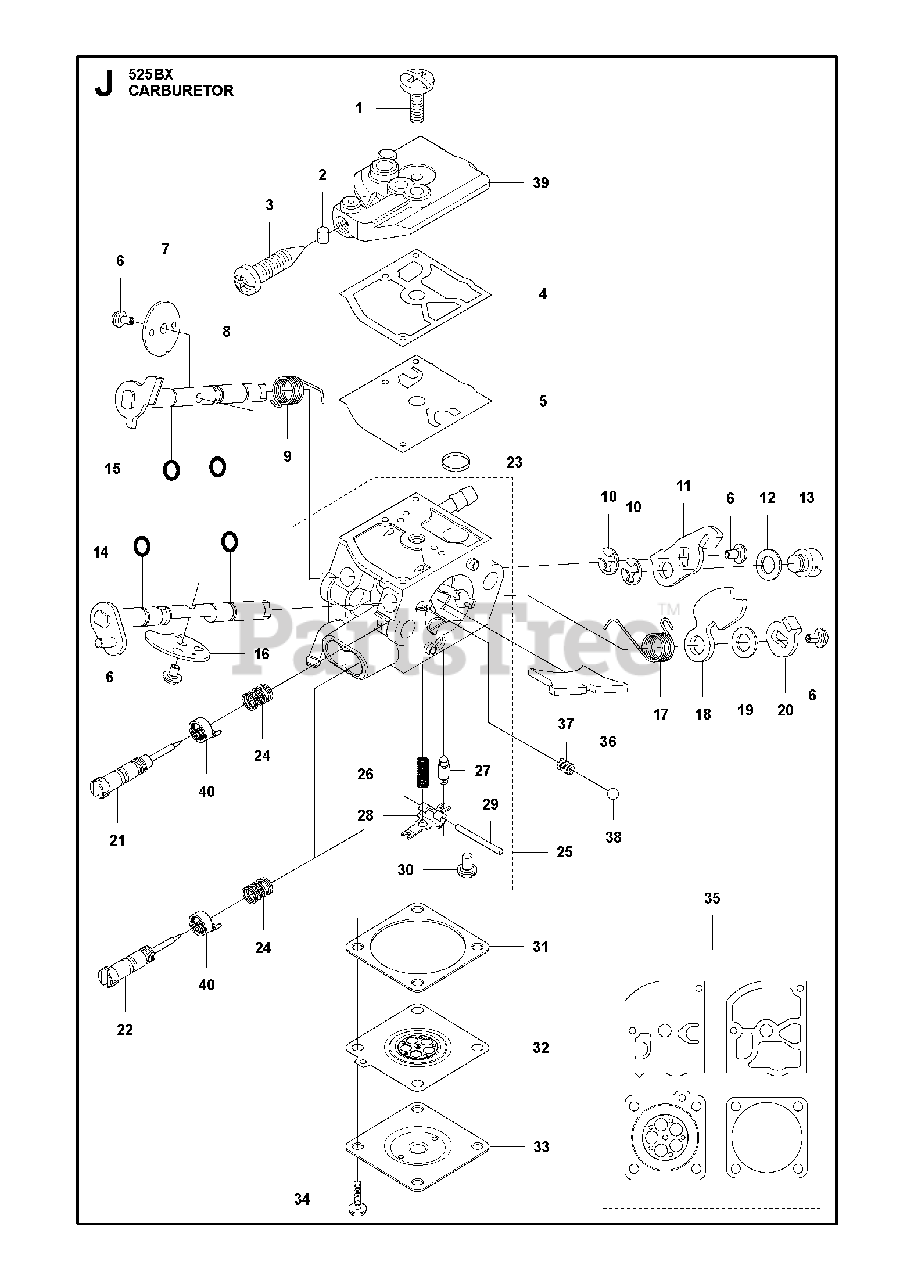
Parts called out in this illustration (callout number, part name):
4	GASKET PUMP
5	DIAPHRAGM PUMP
7	VALVE THROTTLE
8	SHAFT ASSY THROTTLE
9	SPRING THROTTLE RETURN
14	SHAFT ASSY CHOKE
16	VALVE CHOKE
17	SPRING RETURN
21	SCREW IDLE MIXTURE
22	SCREW MAIN MIXTURE
25	BODY ASSY, CARBURETTOR
26	SPRING
27	VALVE INLET
28	LEVER
29	PIN
30	SCREW M3X6
31	GASKET METERING CHAMBER
32	DIAPHRAGM ASSY METERING
33	COVER METERING CHAMBER
34	SCREW M3X7
35	GASKET KIT
36	PLATE SPLIT
37	SPRING FRICTION
38	BALL STEEL
39	PUMP COVER
